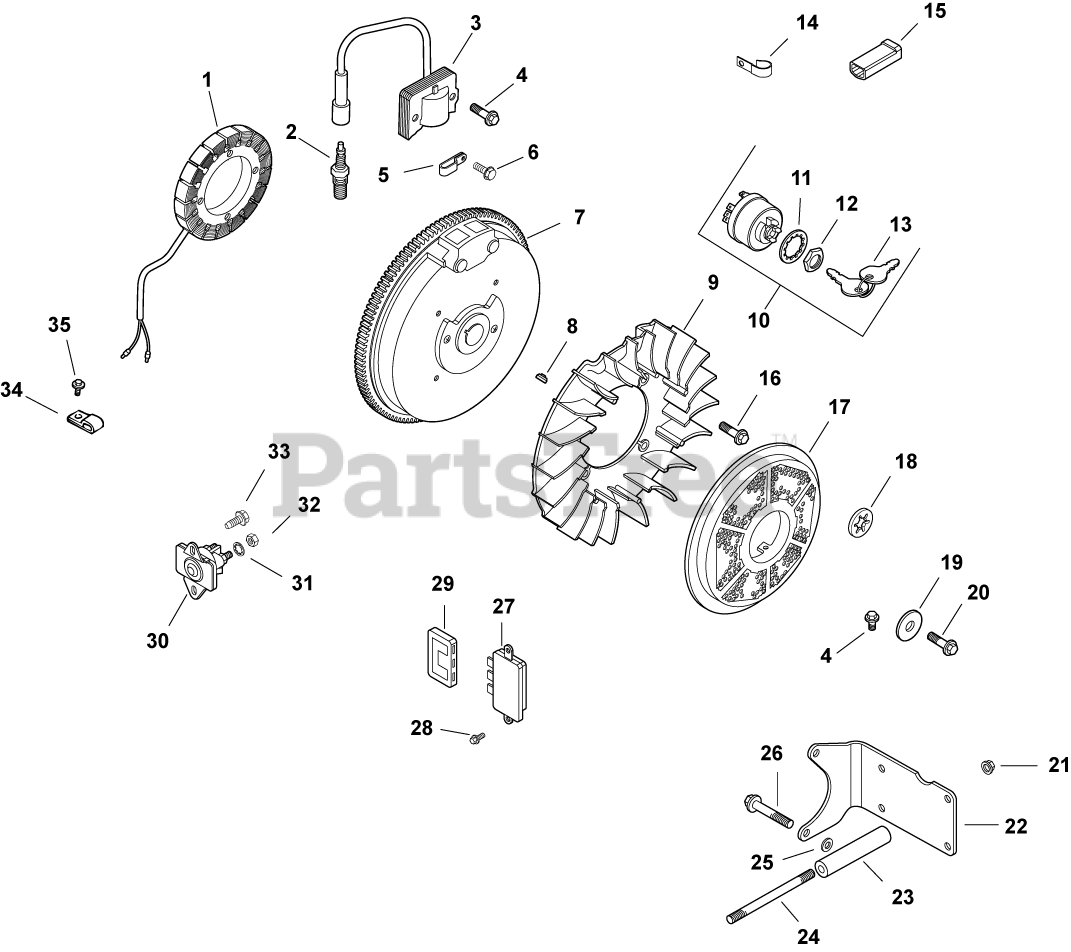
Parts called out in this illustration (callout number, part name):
1	KIT, 15 / 20 AMP STATOR
2	PLUG, SPARK (STD)
3	MODULE, IGNITION
4	SCREW, FLG THD FRM M5X.8X20-(#25086399S)
6	SCREW, FLG THD FRM M5X.8X10
8	KEY, 3/16" X 5/8"
10	SWITCH ASSY, KEY (KM)-USE 25 099 32-S
11	WASHER, INTERNAL TOOTH
12	NUT, KEY SWITCH
13	KEY, SET -USE 48 340 01-S
14	CLIP, CABLE
15	CONNECTOR (1 CONTACT)
16	BOLT, SHOULDER
19	WASHER, FLAT 13/32"
20	SCREW, FLG M10X1.5X45 - (#25086361S)
21	NUT, FLG M8X1.25
22	BRACKET, FUEL TANK
24	STUD, M8X1.25X133-USE 25 755 54-S
25	WASHER, FLAT 11/32"
26	SCREW, FLG M8X1.25X50
27	REG/RECT-15 AMP (KM)-USE 41 403 10-S
28	SCREW, FLG M6X1.0X16
29	CONNECTOR, BODY (KM)-USE 25 155 41-S
30	SOLENOID - WATERPROOF (KM)-USE 25 435 08
31	WASHER, INT TOOTH LOCK 1/4"
32	NUT, JAM 1/4-20 GRADE 2
33	SCREW,FLG THD FRM M6X1.0X16-(#25086397S)
34	CLIP, TUBE & WIRING (KM)
35	SCREW, M5X0.8X25 - (#25086402S)
1251809-S	LEAD, STARTER SOLENOID - DISCONTINUED
2551829-S	LEAD, GROUND SOLENOID
